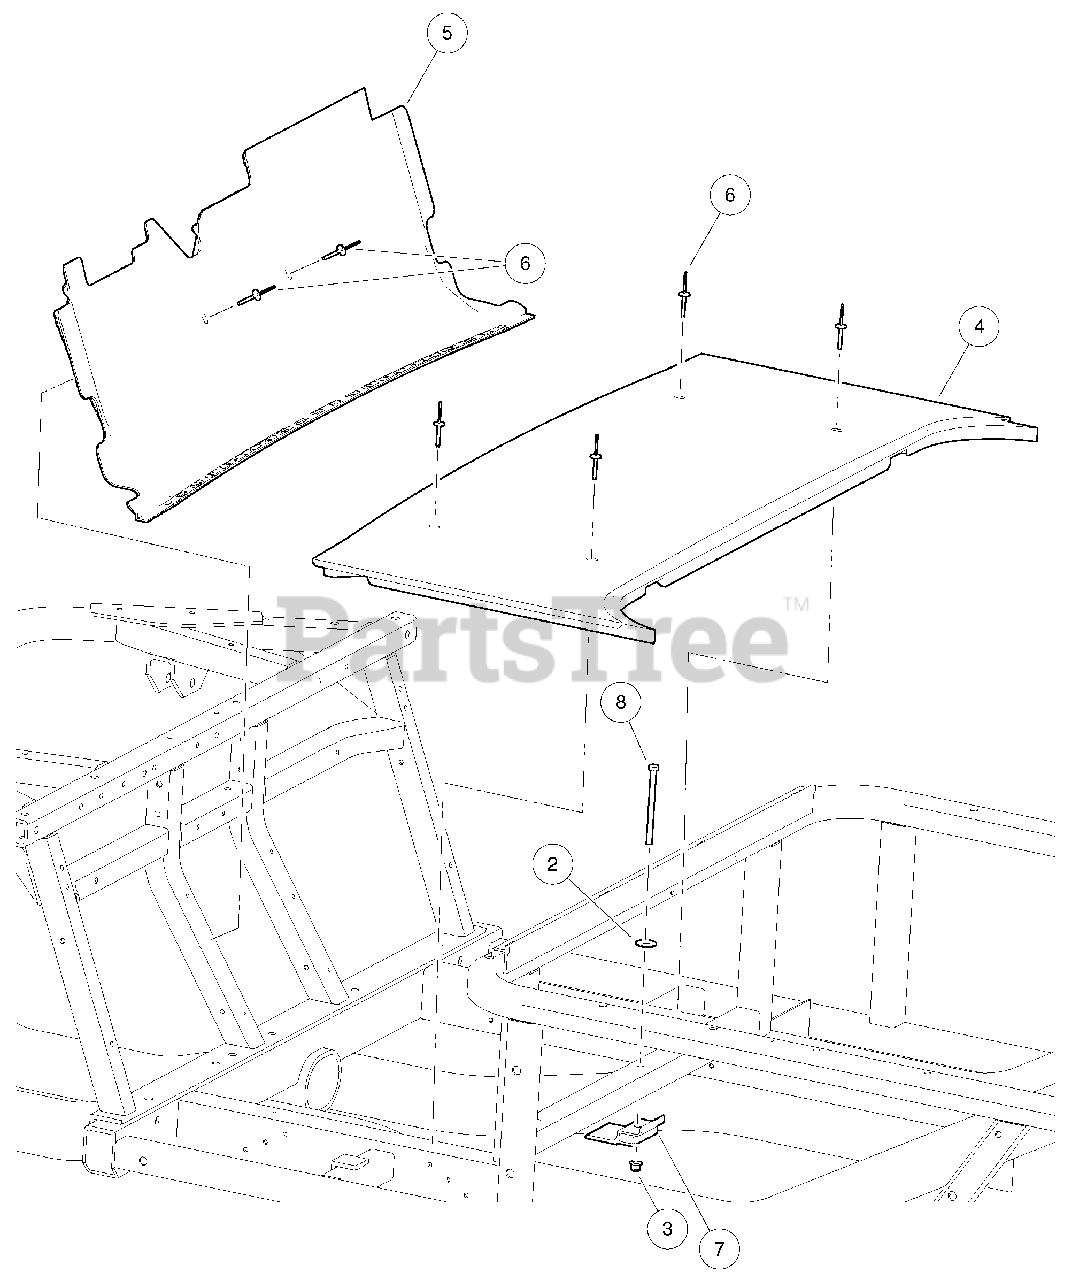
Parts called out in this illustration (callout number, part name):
1	Instl, Floorboard
2	Washer, 5/16 Type B Flat
3	Lock Nut, Flg M8 X 1.25 Nylon
4	Floorboard, Lower
5	Floorboard, Upper
6	3/16 X 1.19 Alum Rivet, Blk
7	Bracket, Support, Floorboard
8	Bolt, M8 X 1.25 X 110
